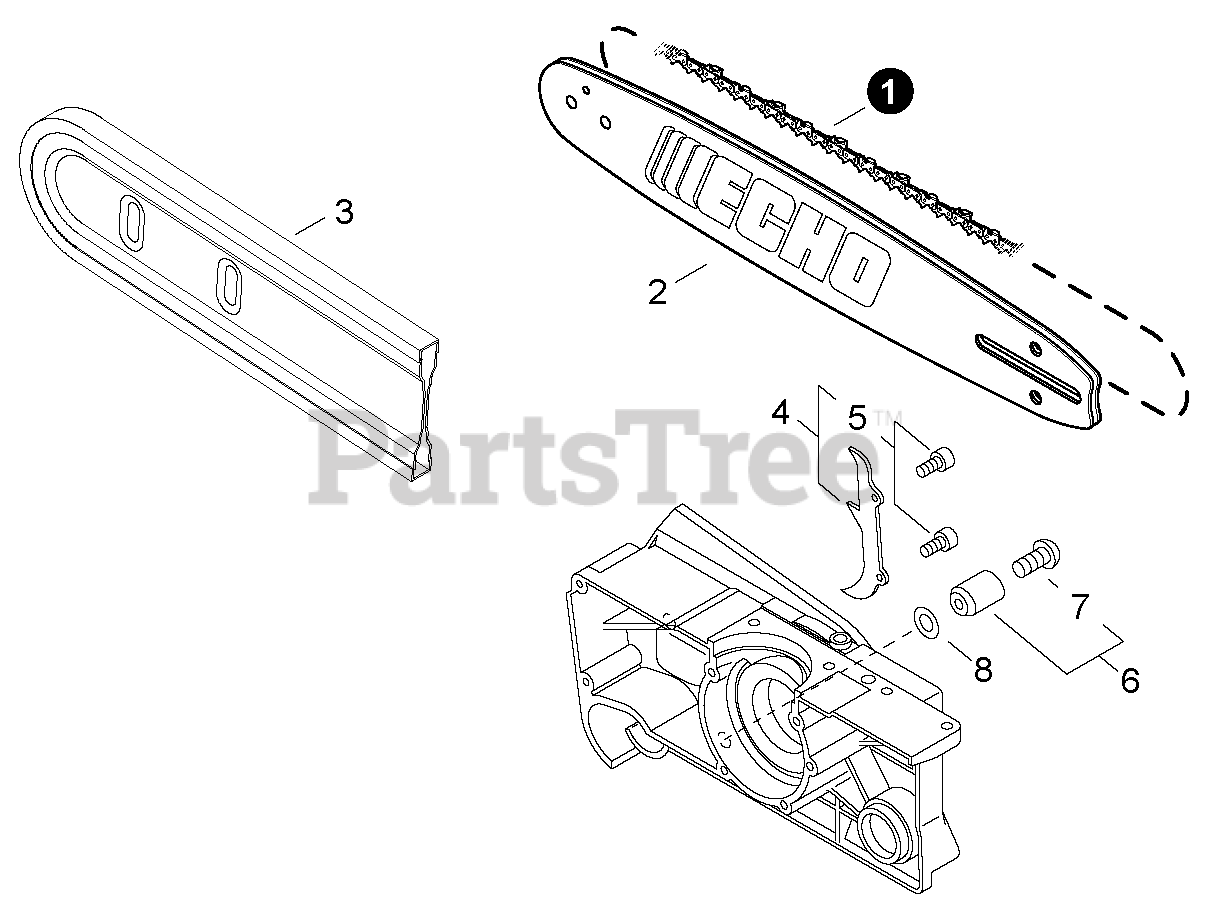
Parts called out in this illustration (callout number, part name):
1	SAW CHAIN - 20" (50cm)
1	SAW CHAIN - 24" (60cm)
1	SAW CHAIN - 28" (70cm)
2	GUIDE BAR - 20" (50cm)
2	GUIDE BAR - 24" (60cm)
2	GUIDE BAR - 28" (70cm)
3	COVER, GUIDE BAR
4	SPIKE KIT
5	SCREW - 5X12
6	CHAIN CATCHER KIT
7	SCREW - 5X18
8	WASHER - 5
